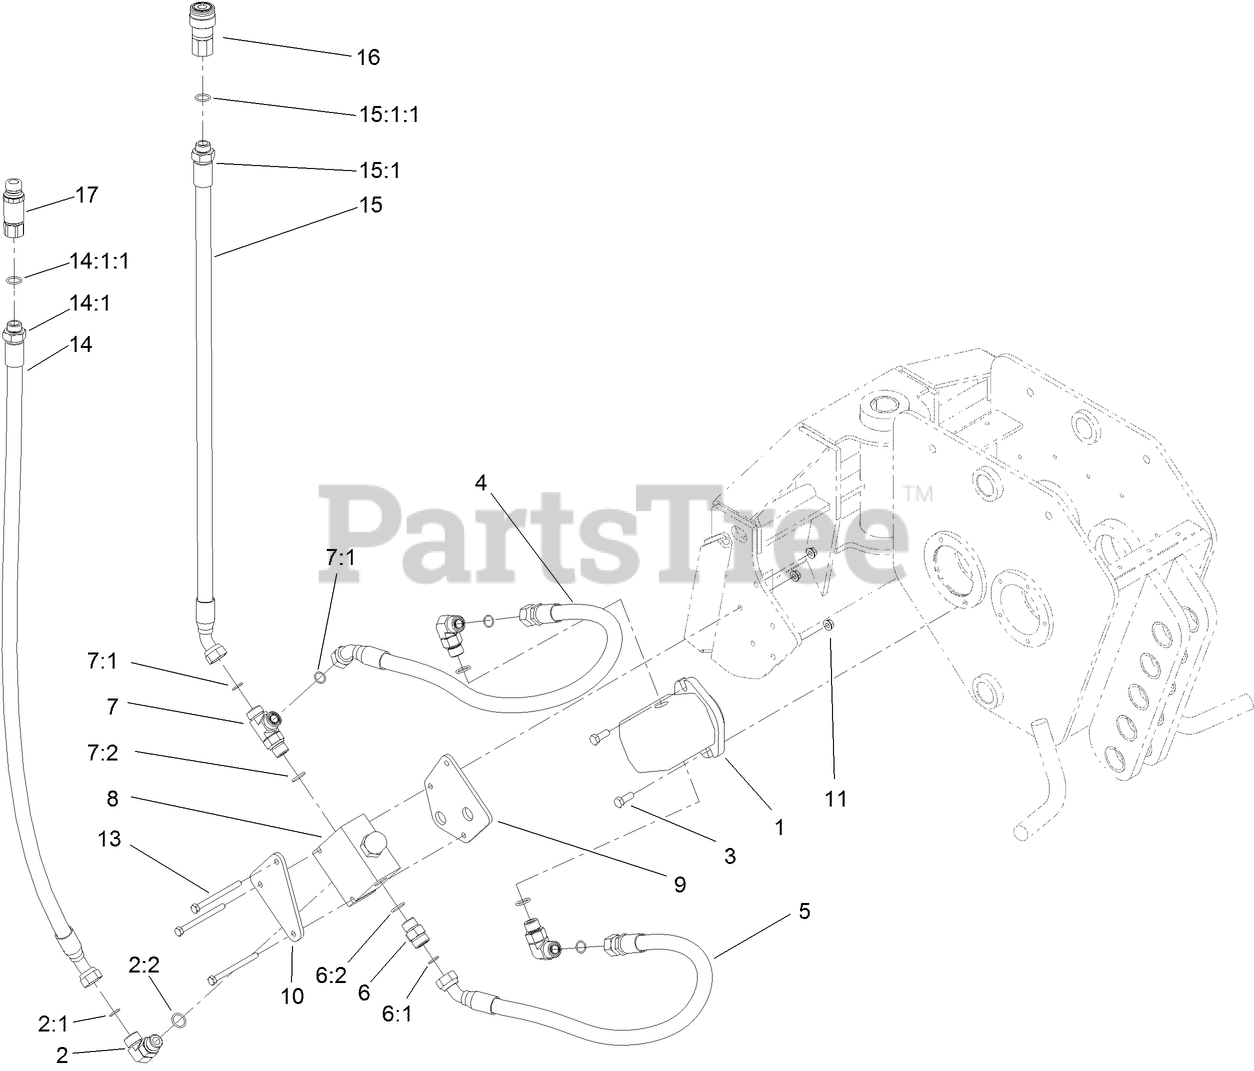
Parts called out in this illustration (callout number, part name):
1	MOTOR-HYD
2	FITTING-ELBOW, 90 DEG
2:1	O-RING
2:2	O-RING
3	SCREW-HH
4	HYD HOSE ASM
5	HOSE-HYD
6	FITTING-STRAIGHT
6:1	O-RING
6:2	O-RING
7	FITTING-TEE
7:1	O-RING
7:2	O-RING
8	FLOW VALVE ASM
9	PLATE-SPACER, VALVE
10	PLATE-CLAMP
11	NUT-HF
13	SCREW-HH
14	HYD HOSE ASM
14:1	FITTING-STRAIGHT
14:1:1	O-RING
15	HYD HOSE ASM
15:1	FITTING-STRAIGHT
15:1:1	O-RING
16	COUPLER-FACE, FLUSH
17	NIPPLE-CONNECT, PRESSURE
